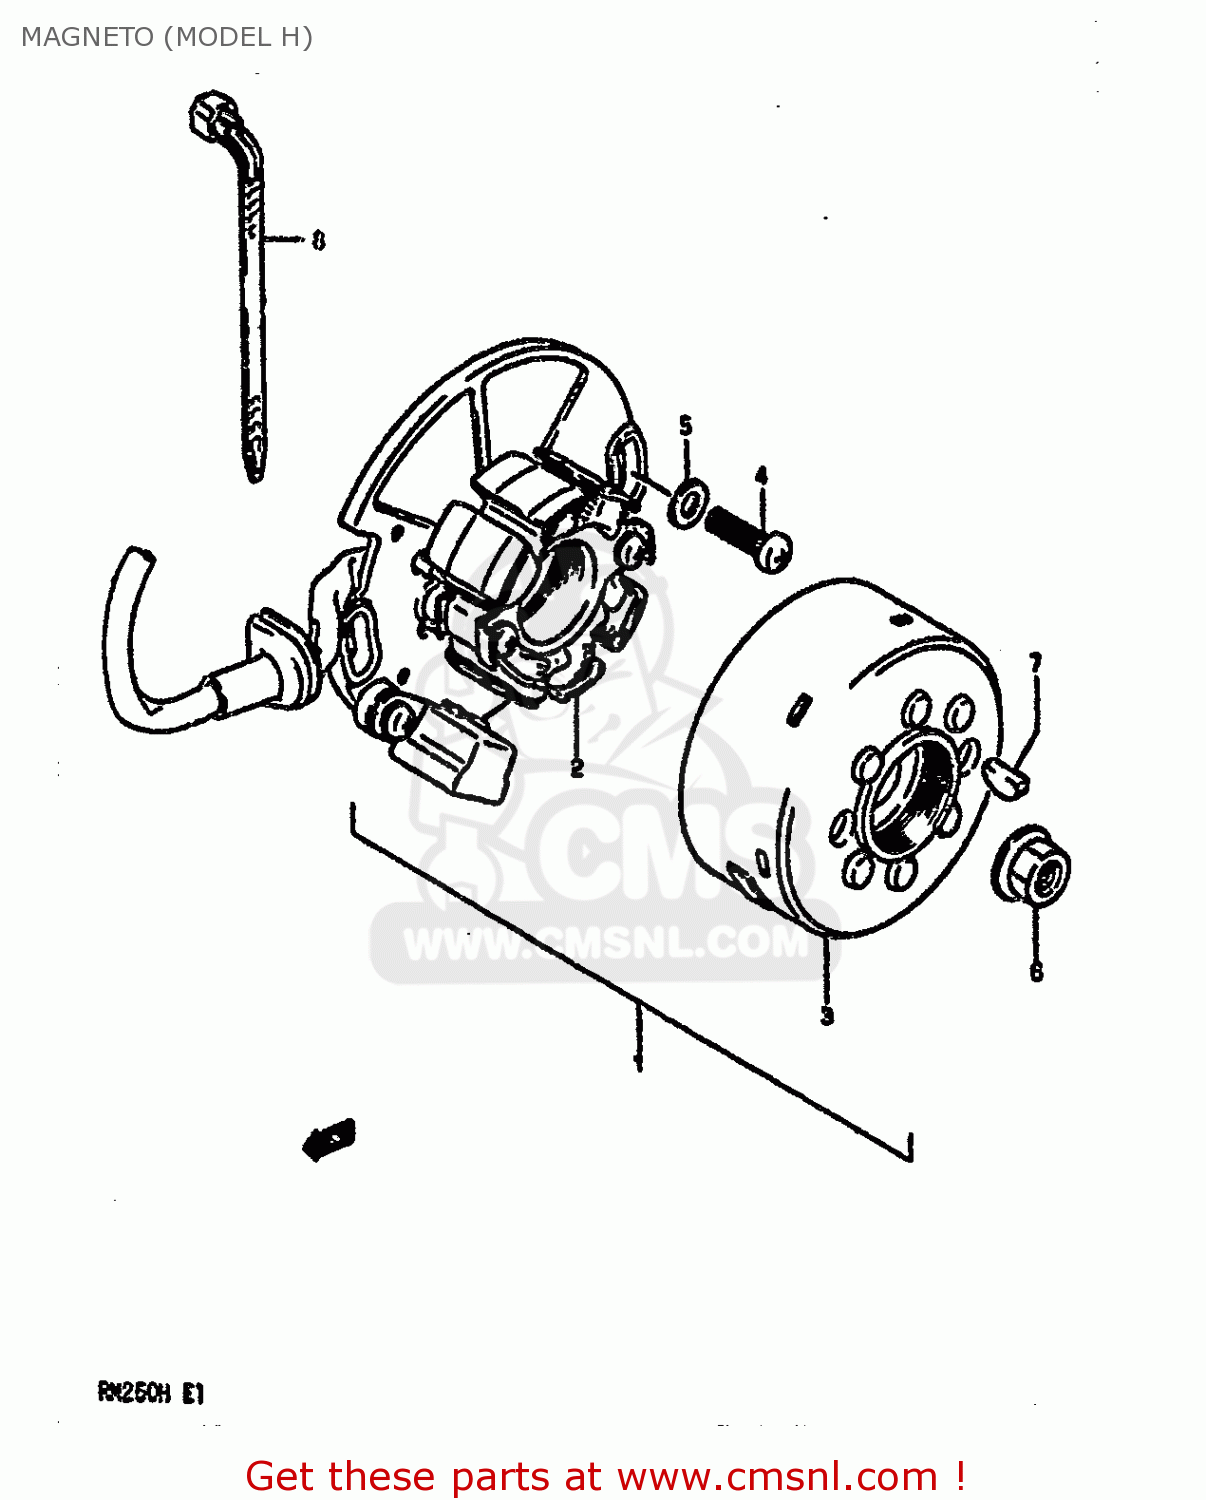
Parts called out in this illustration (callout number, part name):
1	MAGNETO ASSEMBLY
2	STATOR ASSEMBLY
3	ROTOR
4	SCREW
5	WASHER
6	NUT
7	KEY 4MM
8	CLAMP(L:125)
